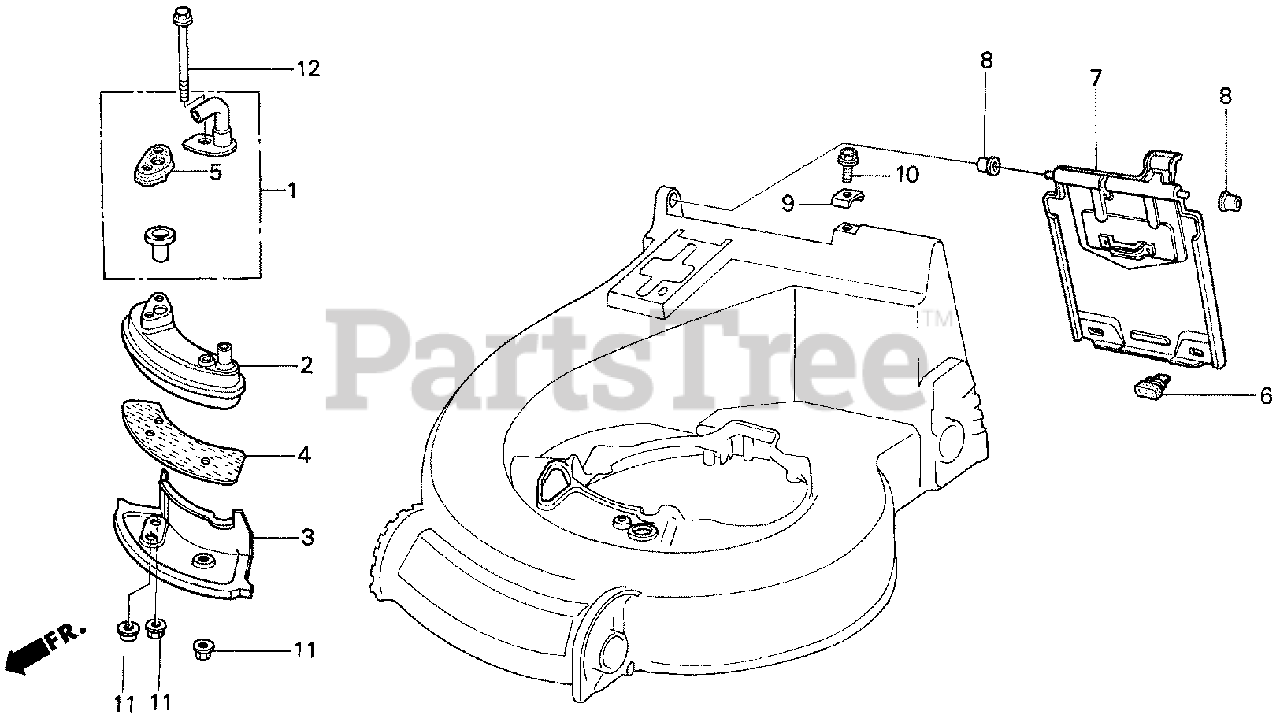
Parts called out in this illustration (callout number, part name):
1	ARRESTER KIT, SPARK (NOT AVAILABLE)
3	COVER, MUFFLER
4	PLATE, MUFFLER (LOWER)
5	LID, MUFFLER
6	STOPPER, DISCHARGE GUARD
7	GUARD, DISCHARGE (NOT AVAILABLE)
8	BUSH, DISCHARGE GUARD
9	HOLDER, DISCHARGE GUARD
10	BOLT, FLANGE (6X25) (CT200)
11	NUT, FLANGE (6MM)
12	BOLT, FLANGE (6X65)
